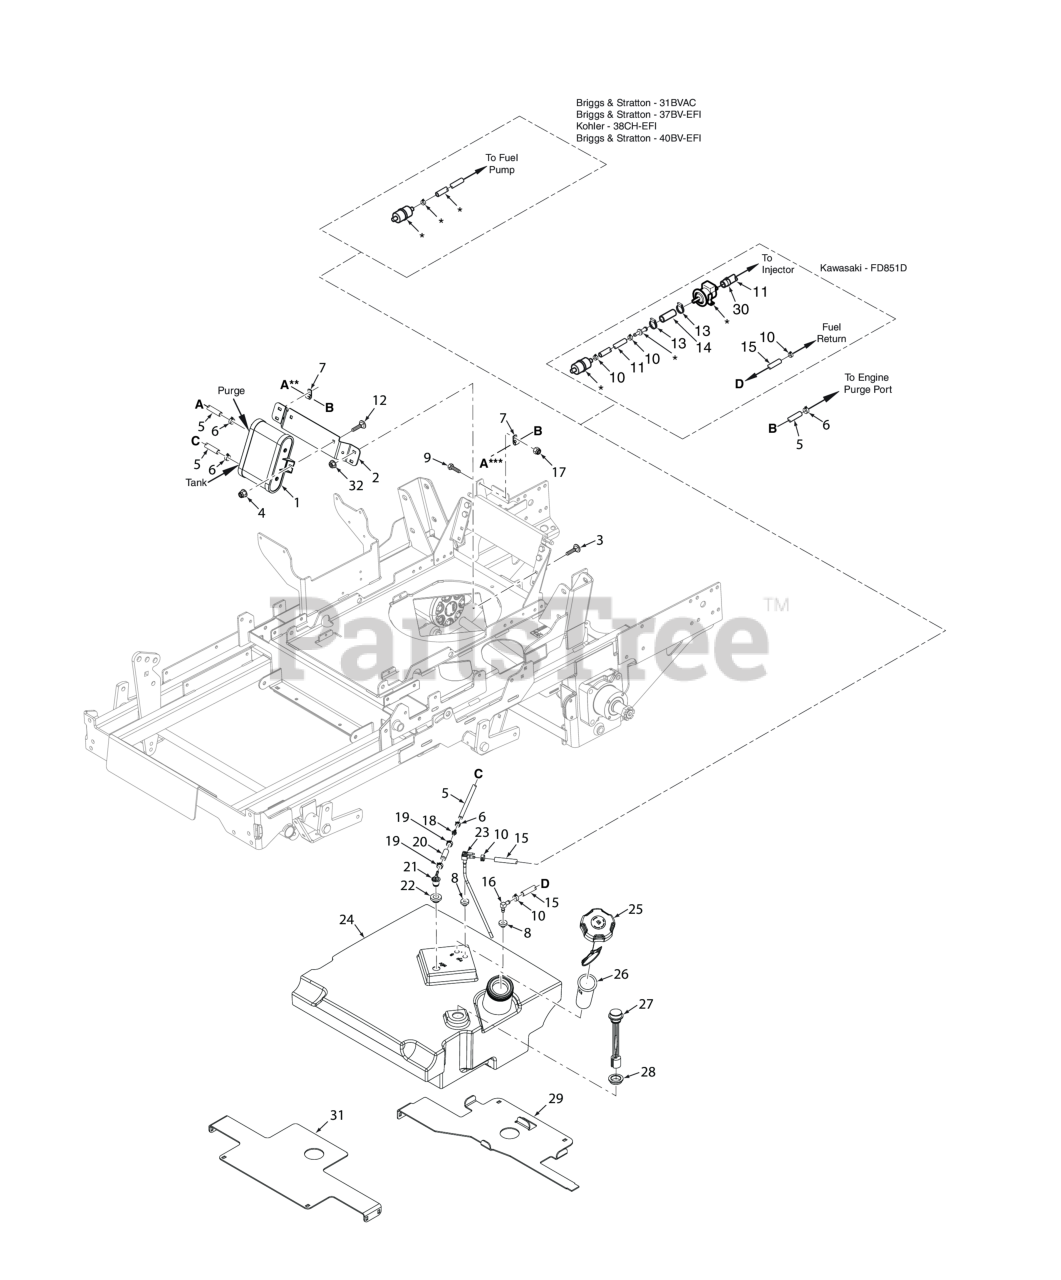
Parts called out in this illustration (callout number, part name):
1	Canister, 1.0 Liter
2	Bracket, Carbon Canister
3	Serr. Fl. Hex Head CPSCR, 1/4-20 x 3/4"
4	Nut, Flange Head Elastic Stop 5/16-18
5	Hose, Vapor Recovery 3/16" (order by inch)
6	Clamp, Vapor Recovery Hose 3/16"
7	Clamp, Cable - .375 Dia.
8	Bushing, 0.56" Dia. Viton
9	Capscrew, Hex Head 1/4-20 x 1"
10	Clamp, Fuel Hose 1/4" Hose I.D.
11	Fuel Hose, 5/16" I.D. Non-Perm (791DFI) - Order by Inch
12	Bolt, 5/16-18 x .75 RHSN Carriage
13	Clamp, Cable 3/4" I.D.
14	Fuel Hose, 1/2" I.D. Non-Perm - Order by Inch
15	Fuel Hose, 1/4" I.D. Non-Perm (791DFI Fuel Return) - Order by Inch
16	Return Fitting
17	Nut, Flanged Elastic Stop 1/4-20
18	Mender, 1/4 x 3/16 w/0.02 Hole
19	CLAMP, FUEL HOSE(KAWASAKI ONLY)
20	Hose, 1/4" Vapor Recovery (order by inch)
21	Remote Vent, No Valve
22	Grommet, Viton,
23	Valve, Fuel Shutoff
24	Fuel Tank Assy. - Kawasaki DFI
25	Fuel Cap w/ Tether (E.P.A.)
26	Tube, Fuel Tank Insert - 6"
27	Fuel Guage Assy., 8"
28	Grommet, Fuel Gauge
29	Rear Support, Fuel Tank
30	Clamp, .69" Max. / .25" Min. Dia.
31	Front Support, Fuel Tank
32	NUT, 1/4-20 SERRATED FLANGE HEX HEAD
